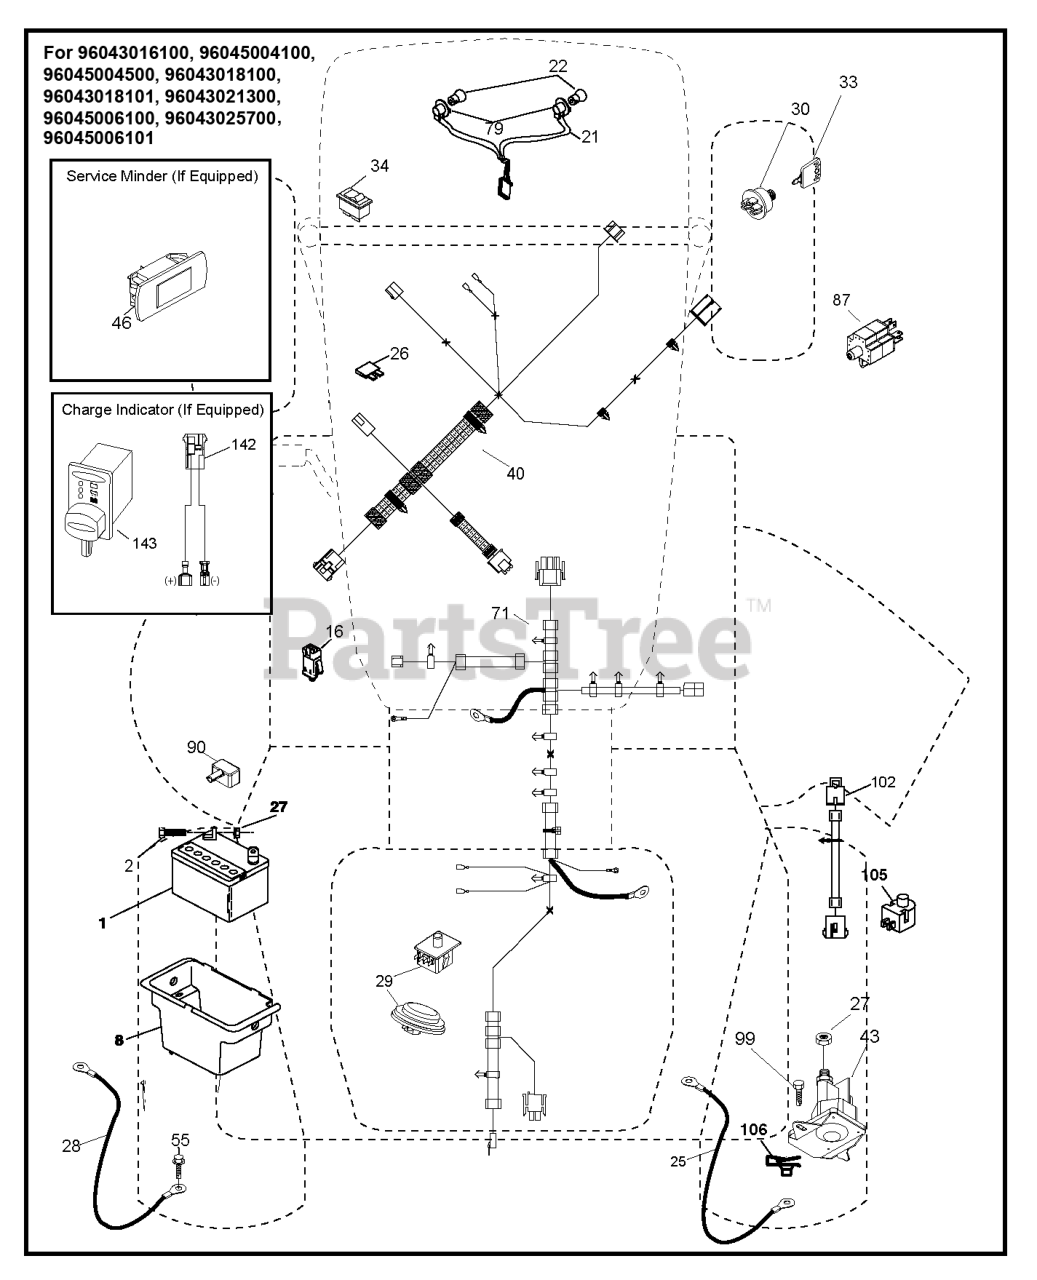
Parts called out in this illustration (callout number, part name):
1	Battery 12 Volt 25 Amp
2	BOLT.HEX.1/4.X.3/4.DICHROMATE
8	BOX.BATTERY.MNT.REAR.L
16	SWITCH INTERLOOK PUSH-IN
21	HARNESS.LIGHT W/4152J BULBS
25	CABLE.BATT.RED.8GA.17
26	FUSE 20AMP
27	Hardware
27	NUT
28	CABLE.GROUND.REAR.BATTERY.8G
29	SWITCH.SEAT.DELTA.OPC.
30	SWITCH.IGN.DELTA.W.LGH.ROS
33	KEY.CHAIN.BLISTER.PACK.GEN.USA
33	KEY.CHAIN.BLISTER.PACK.GEN.INT
40	HARNESS.TEX.DASH.MAN.REAR BATT
40	HARNESS.DASH.CC.RRBATT.RDYSTRT
43	SOLENOID.STARTER.BRASS.PLUNGER
43	Solenoids
46	GUAGE.SRVCMNDR.HRMTR.
55	SCREW 5/16"
71	HARNESS.CHASSIS.RRBATT.RDYSTRT
71	HARNESS.TEX.CHSSIS.REAR.BATT
79	BULB HOLDER ASM.
87	SWITCH.INTRLCK.CLUTCH.
90	COVER.TERMINAL.BATTERY
99	SCREW HEXWSHR 1/4-20X3/4
102	HARNESS PIGTAIL PCH TEX ROS
105	REVERSE SWITCH
106	1/4-20 U NUT
